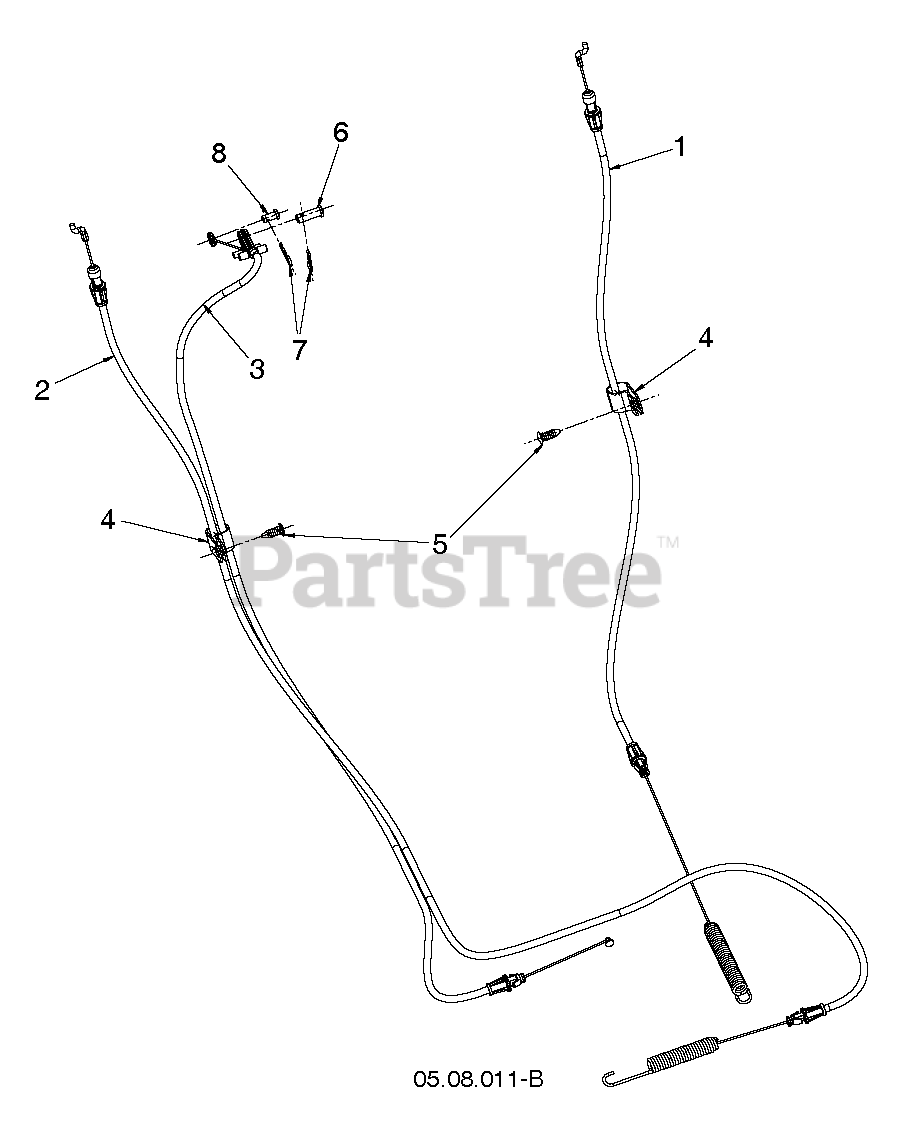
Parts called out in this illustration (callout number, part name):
1	Drive Control Cable, 16
2	Auger Control Cable
3	Speed Control Cable, DSST OPP
4	CLIP.CABLE.BLK
5	FASTENER.PUSH.O.250X0.783
6	Clevis Pin, 5/16 X .875
8	Clevis Pin, .25 X .31
